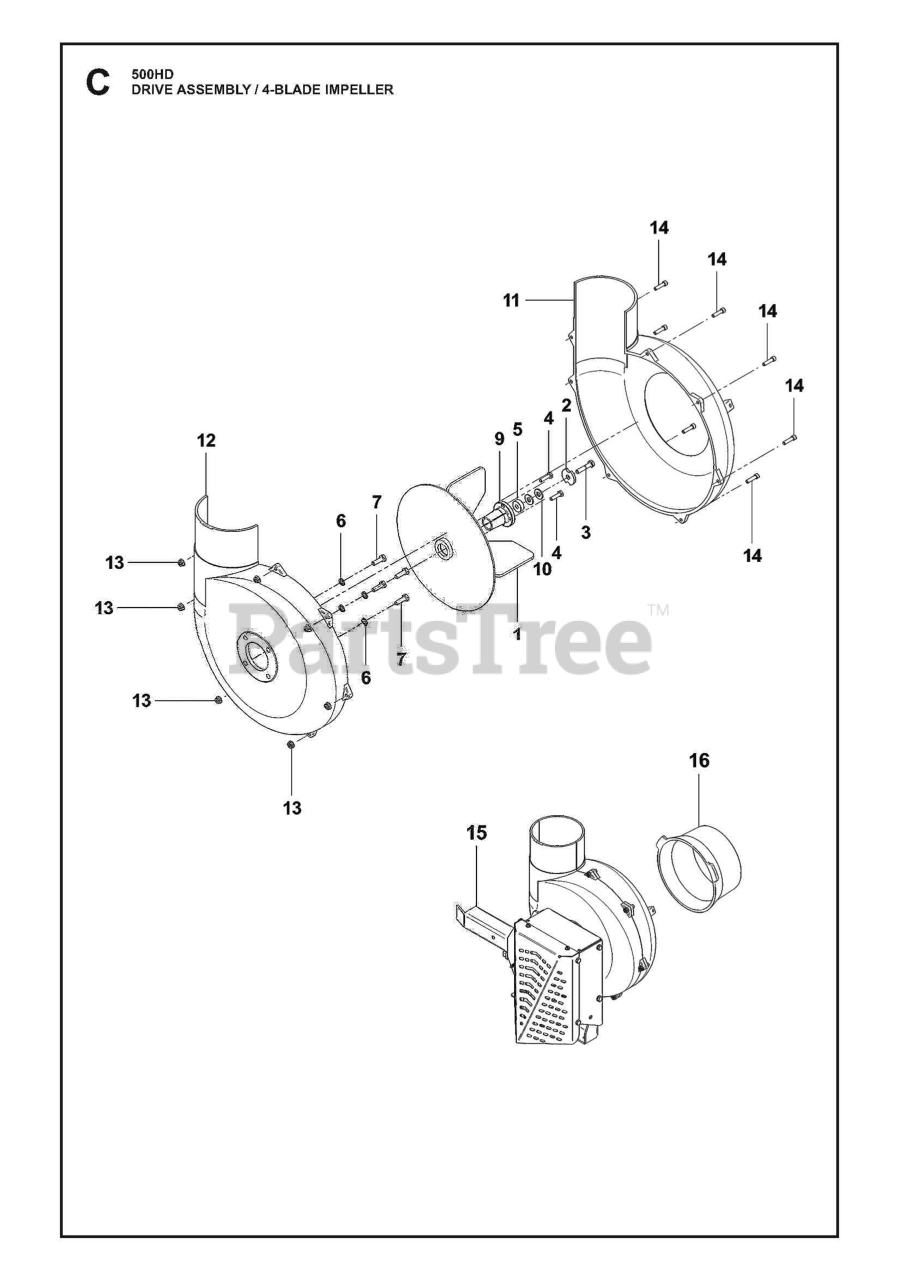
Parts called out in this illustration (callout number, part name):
1	IMPELLERS
2	WASHERS
3	BOLTS
4	BOLTS
5	BUSHINGS
6	WASHERS
7	Bolts
9	BUSHINGS
10	WASHER 11/32 X 11/16 X 14 GA T
11	HOUSINGS
12	HOUSINGS
13	NUT HEX_LRG FLG_1_4-20_LOCK
14	SCREW HEX WASH THDRL BLK 1_4-
15	IMPELLERS
16	ADAPTERS
